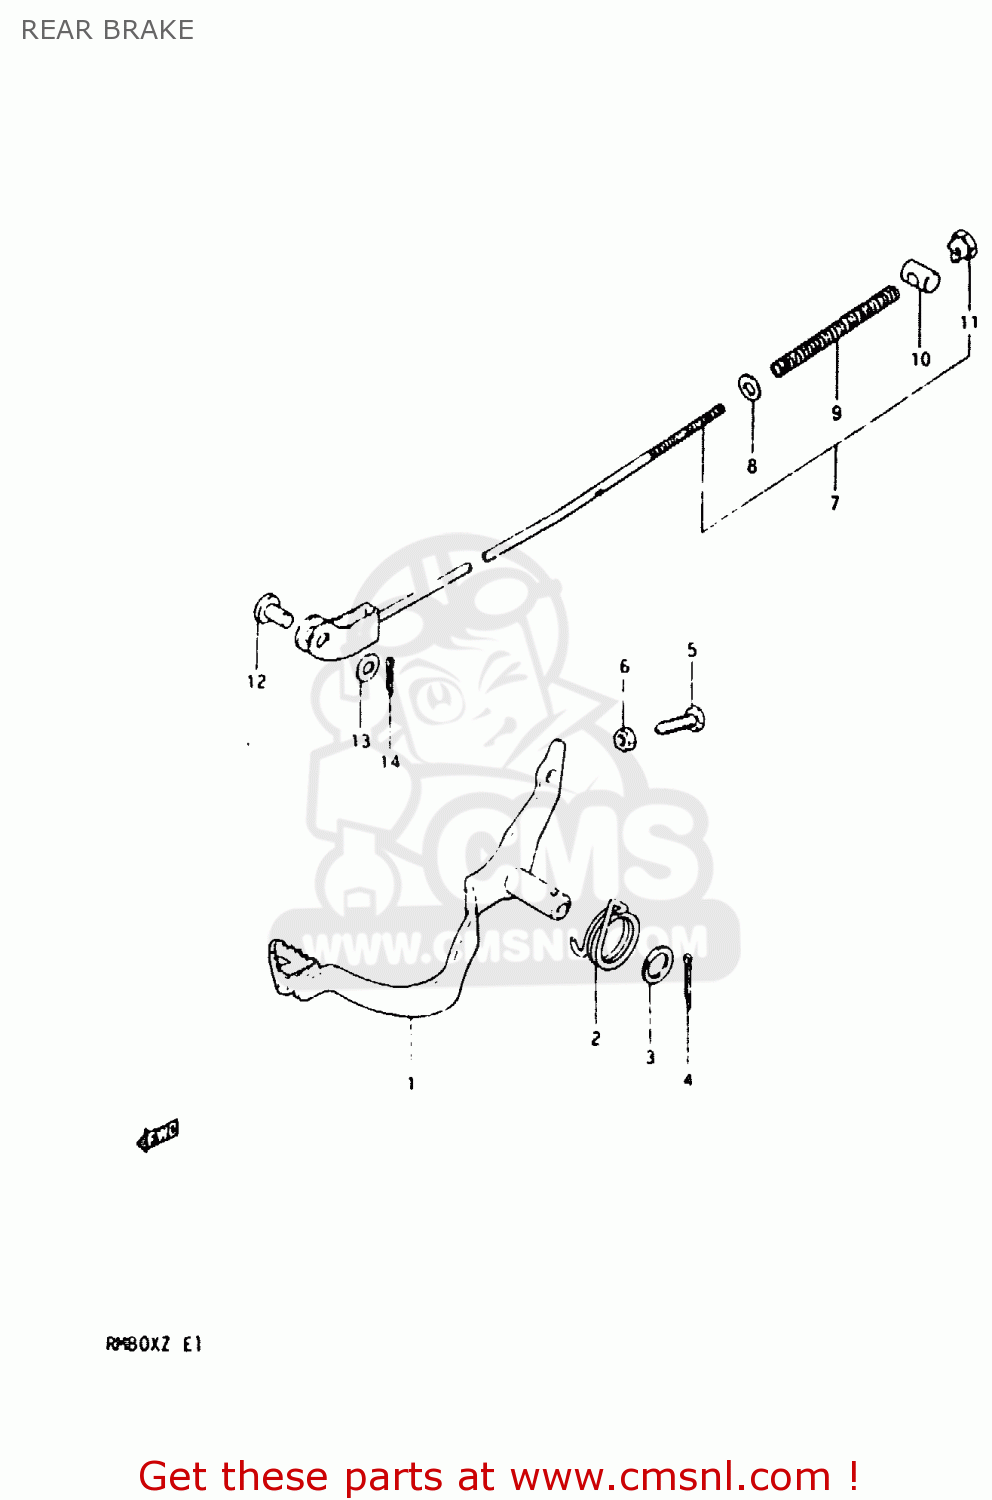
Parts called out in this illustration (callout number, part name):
1	PEDAL,BRAKE
2	SPRING
3	WASHER(15.5X26X2.3)
4	COTTER PIN
5	SCREW(6X23)
6	NUT
7	ROD ASSEMBLY,REAR BRAKE
8	WASHER
9	SPRING
10	PIN(11X18)
11	NUT
12	PIN
13	WASHER
14	PIN 20X20
